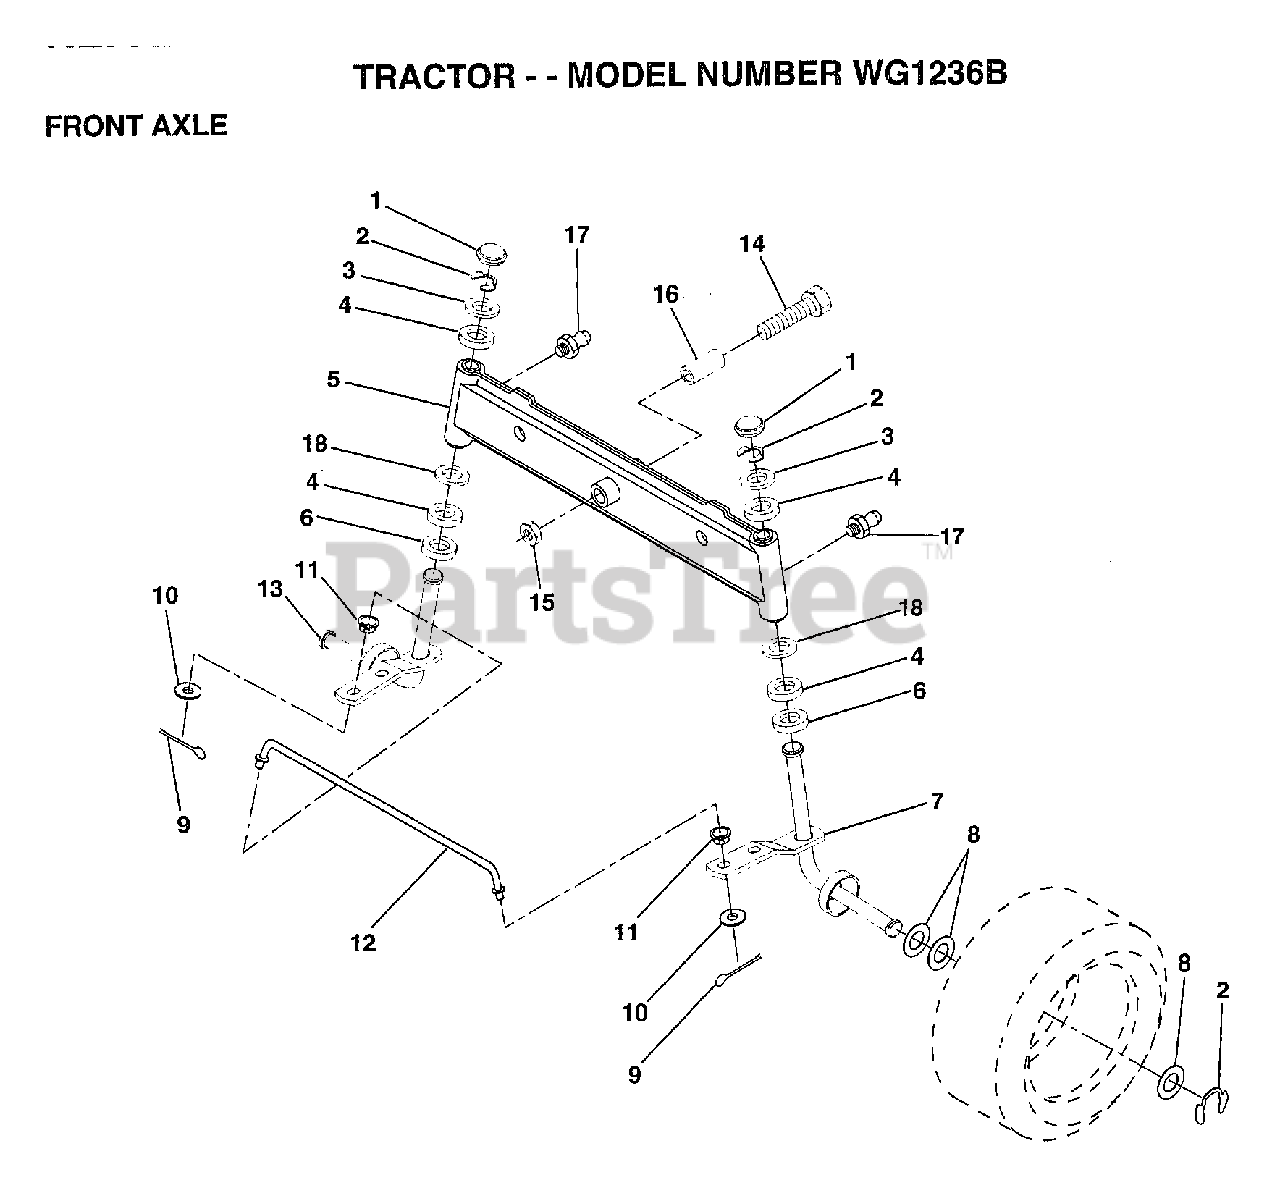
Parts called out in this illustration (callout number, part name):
1	CAP
2	RING
3	WASHER
4	COL. SRTG. BEAR.
5	AXLE ASM FRONT
6	WASHER .T
7	SPINDLE ASM RH
8	WASHER
9	COTTER PIN
10	WASHER
11	BUSHING.DRAGLINK
12	TIE ROD
13	SPINDLE ASM LH
14	BOLT HEX 5/8-11
15	"NUT-LOC,FLANGE LT"
16	BEARING
17	ZERK M
18	WASHER
